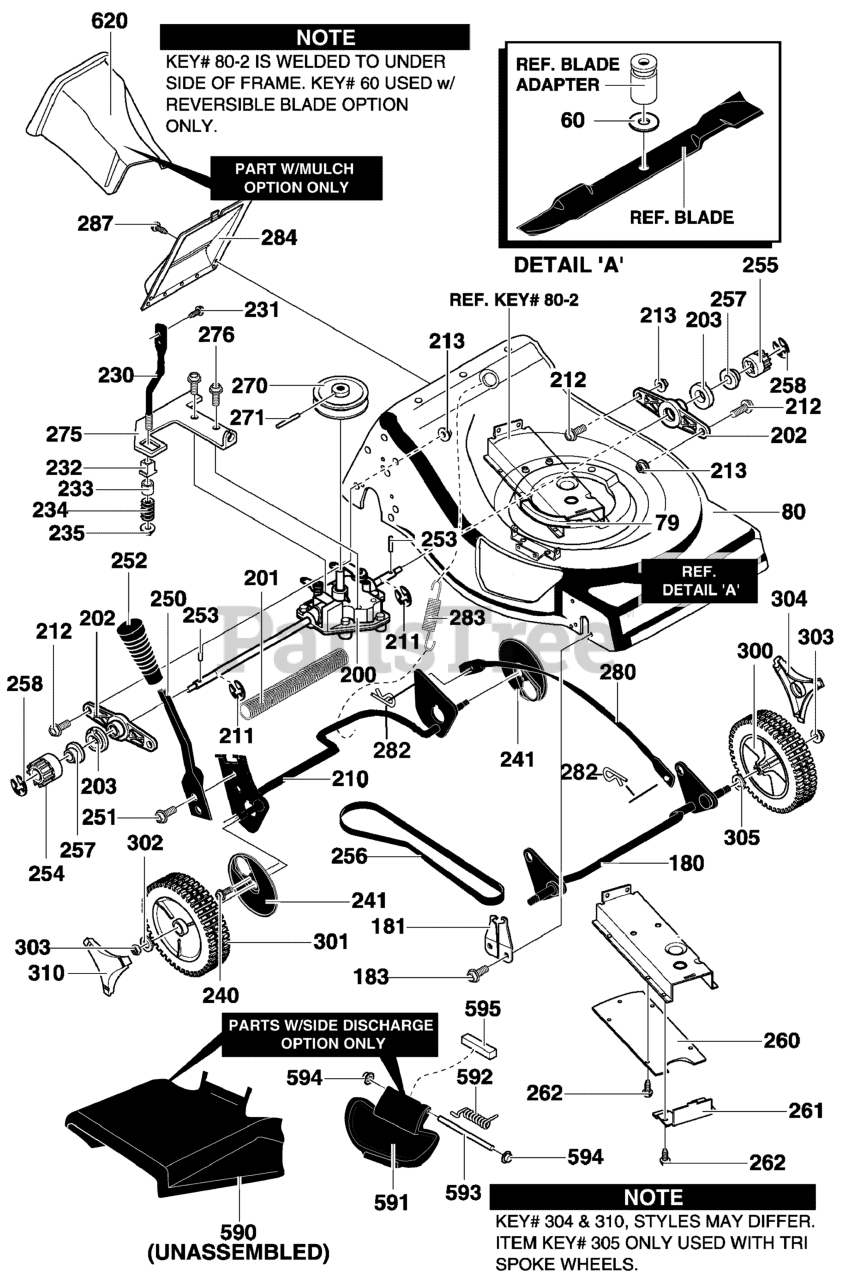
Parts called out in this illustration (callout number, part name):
60	SPACER
79	SEAL, FOAM
80	ASSY, FRAME
180	CROSSBAR, FRONT
181	BUSHING
200	TRANSMISSION
201	SHIELD, AXLE
202	SUPPORT, AXLE
203	BEARING, LIFTER
210	ASSY, CROSSBAR
211	E-RING
212	SCREW
230	SUPPORT, SPRING
232	BUSHING
233	SPACER
234	SPRING
235	NUT, 5/16-18
241	DUST COVER
250	LEVER, SPRING
251	SCREW
252	KNOB, HEIGHT ADJ
253	PIN, DRIVE
254	GEAR, PINION RIGHT
255	GEAR, PINION LEFT
256	BELT, V
257	WASHER, FLAT
258	E-RING
260	COVER, BELT GUARD
261	COVER, FRONT BELT
270	PULLEY
271	PIN, SPRING
275	BRACKET, CABLE
280	LINK, LIFTER ASSY
282	PIN, HAIR
283	SPRING, EXTENSION
284	COVER, REAR
287	SCREW
300	TIRE & RIM
301	WHEEL, DRIVE
302	WASHER, FLAT
303	NUT
304	HUB CAP
305	SPRING WASHER
310	HUB CAP
590	DEFLECTOR, CHUTE
591	COVER, MULCH
592	SPRING, TORSION
593	ROD, PIVOT
594	CAP, PUSH ON
595	SEAL, FOAM
620	PLUG, MULCHER
